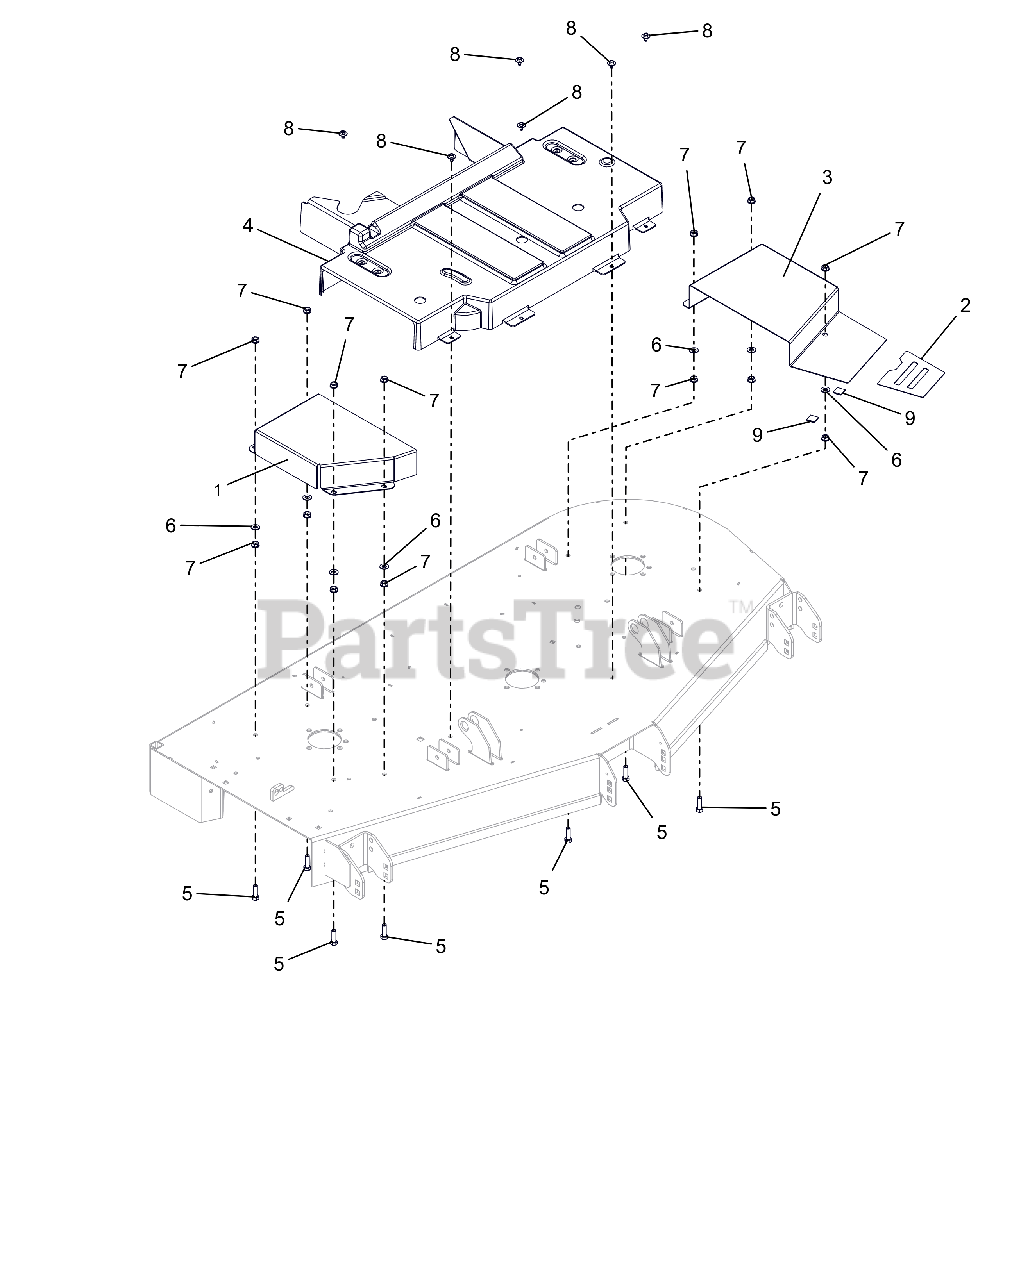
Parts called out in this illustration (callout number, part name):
1	GUARD,BELT 52" RIGHT CE
2	GRIP TAPE 52-60 BELT COVER
3	GUARD, BELT 60" LEFT CE (ORANGE)
4	GUARD, CENTER DECK SPINDLE CE
5	BLT, HEX .38-16X1.25 G5 ZCC
6	WSHR,FLT .406X.812X.065 ZCC
7	NUT, SPNLK-FLG .38-16 G5 ZCC
8	SCR, TAP .25-20X.50 LG HWH ZCC
